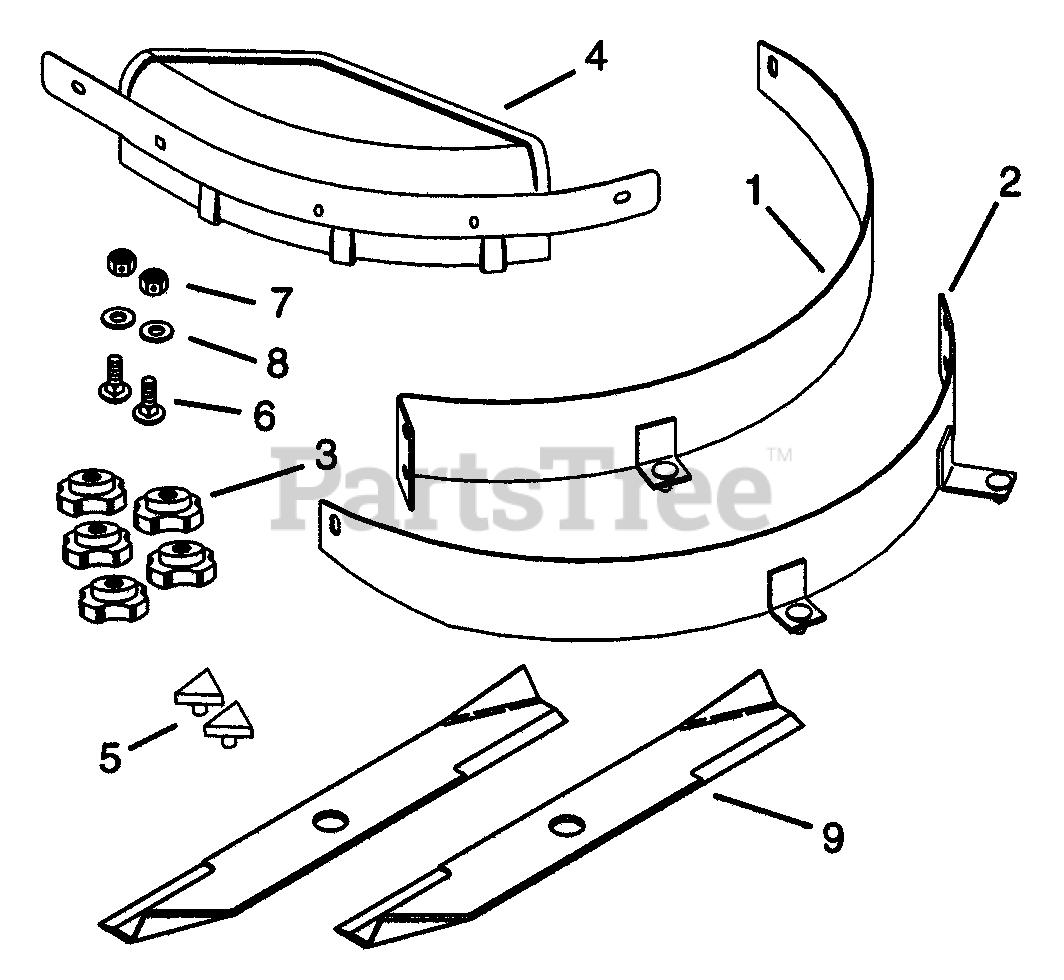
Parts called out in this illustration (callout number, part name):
1	WELDMENT, MULCH BAFFLE RH
2	WELDMENT, MULCH BAFFLE LH
3	KNOB
4	ASSY, MULCH COVER 42"
6	@BLT-RDHDSQNK .31-18X.75 G5YZ
7	@NUT-LK-CTR .31-18 YWZC
8	@WSHR-FL-STL.38X.875X.083 YWZC
9	BLADE, MULCH 22"
